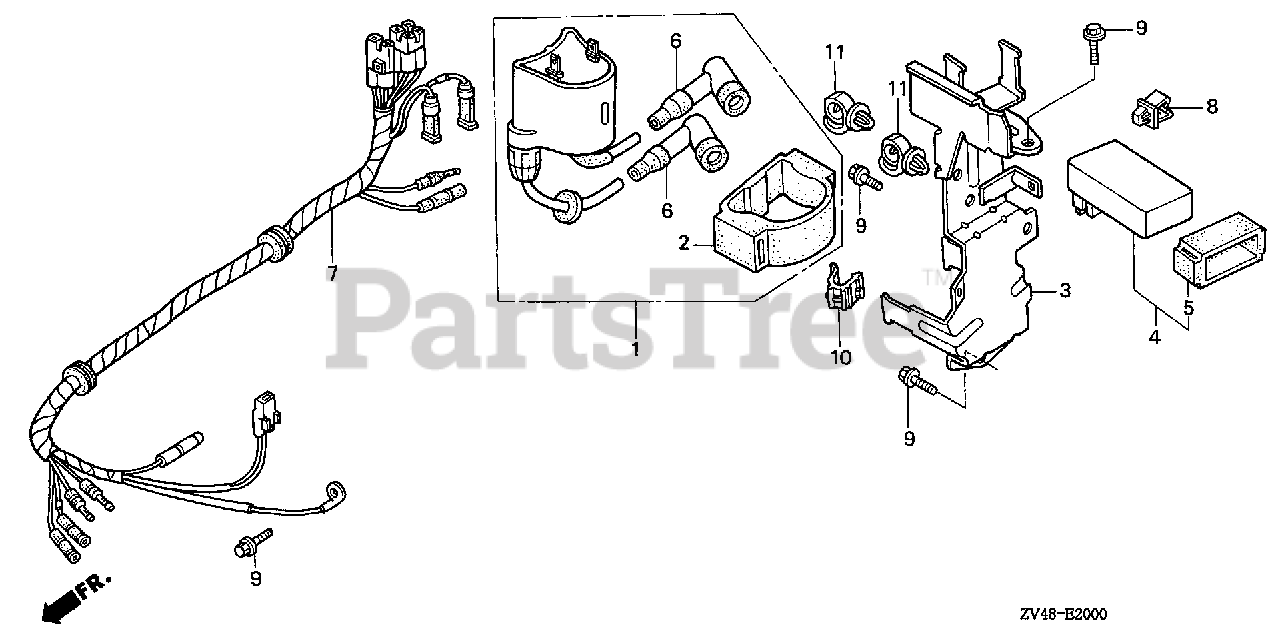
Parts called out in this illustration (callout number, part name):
1	COIL ASSY., IGNITION
2	SUSPENSION, IGNITION COIL
3	BRACKET, IGNITION COIL
4	MODULE, IGNITION CONTROL (CDI)
5	CUSHION, IGNITION CONTROL MODULE (CDI)
6	CAP ASSY., NOISE SUPPRESSOR
7	WIRE HARNESS ASSY.
8	CLIP B, AIR TEMPERATURE SWITCH WIRE
9	BOLT, FLANGE (6X12)
10	CLIP, WIRE HARNESS
11	CLIP, WIRE HARNESS (25MM)
